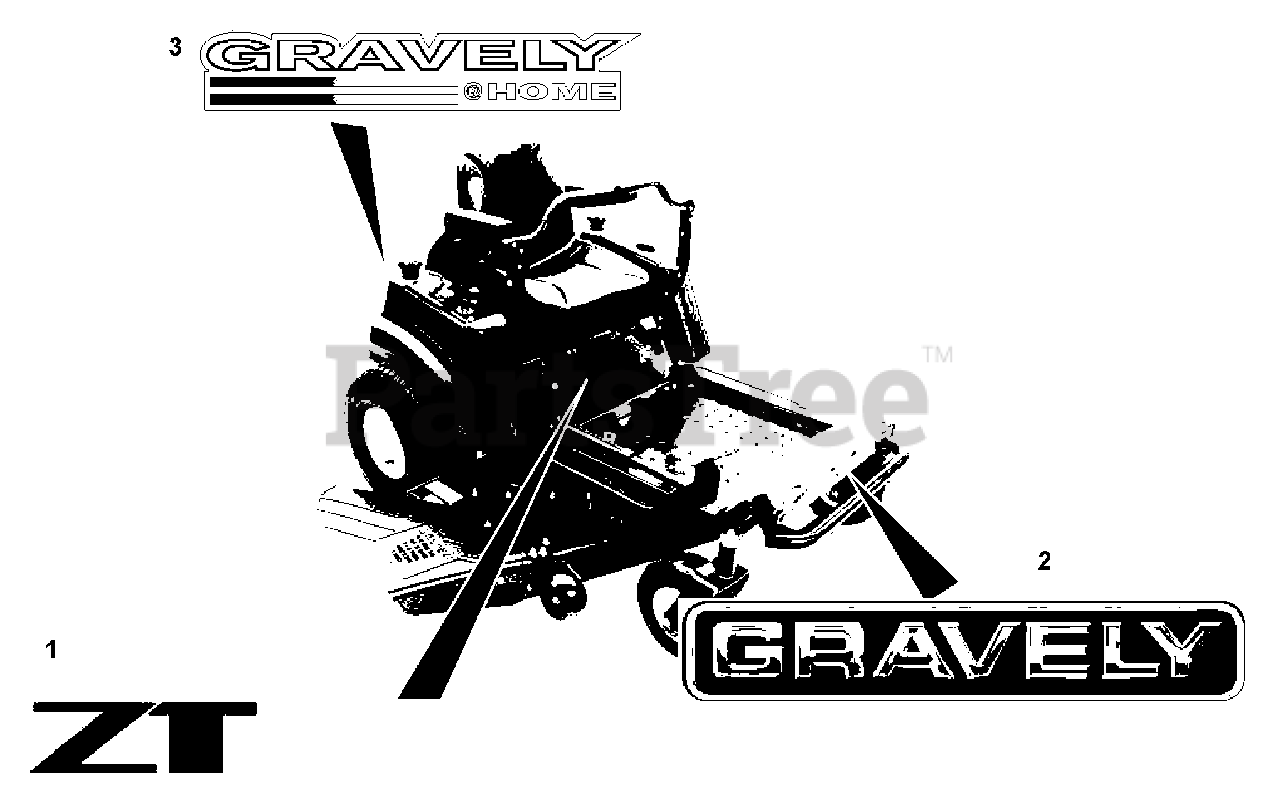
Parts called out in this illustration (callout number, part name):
1	Decal-ZT 1540 (042)
1	Decal-ZT 1740 (044)
1	Decal-ZT 1944 (046)
1	Decal-ZT 2148 (048)
1	Decal-ZT 2352 (050)
2	Decal-Gravely Jewel
3	Decal, Gravely @ Home
